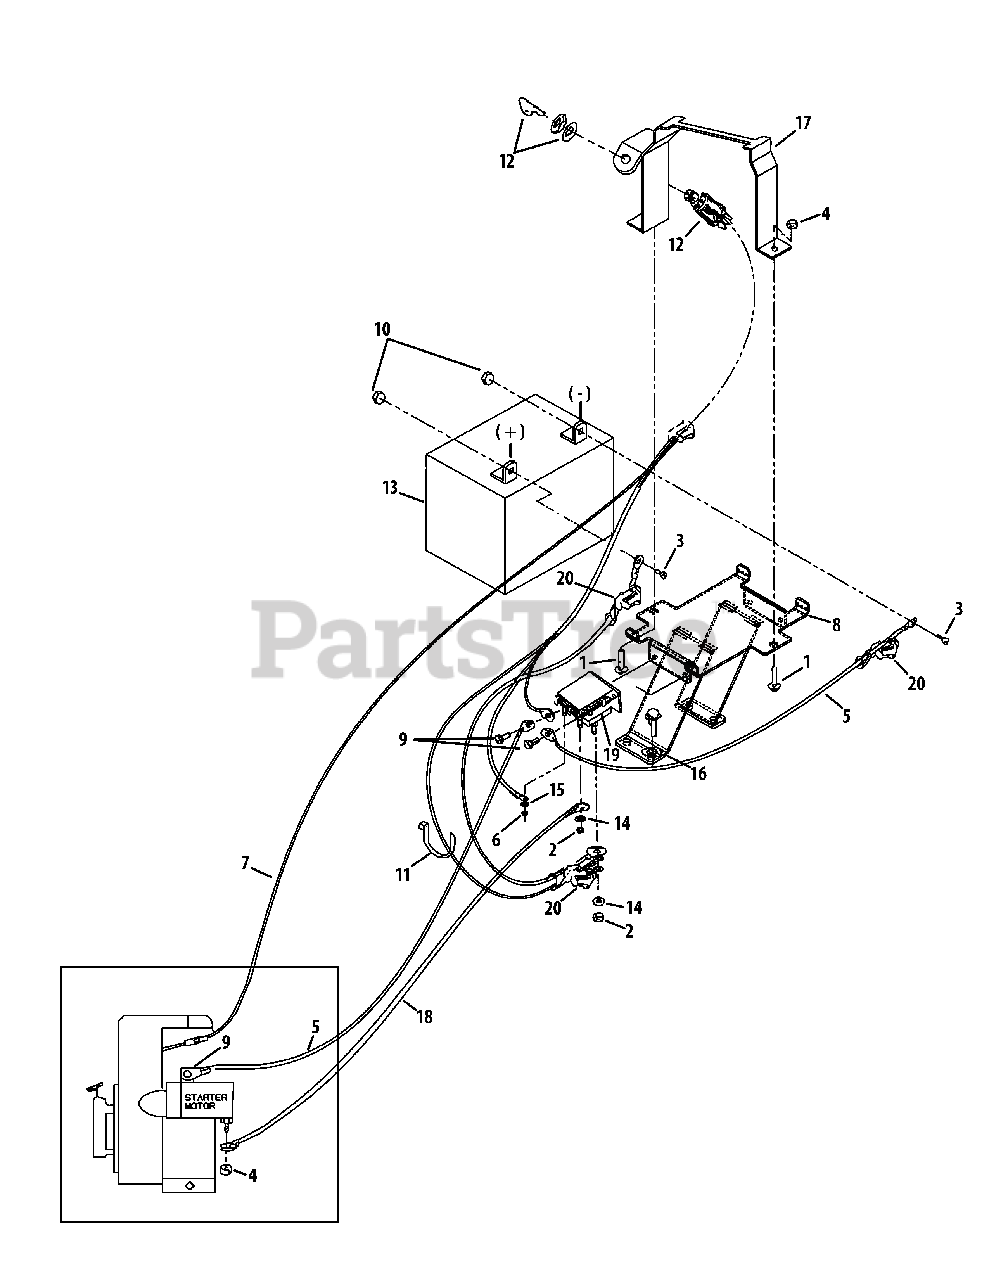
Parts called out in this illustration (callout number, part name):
1	Carriage Screw 1/4-20 x 1.25
2	Hex Nut 5/16-24
3	Flange Screw 1/4-20 x .625
4	Hex Locknut 1/4-20
5	Cable (Ground Wire)
6	Hexlock Washer Nut, 10-32
7	Electric Start Harness
8	Battery Bracket Assembly
9	Self-tapping Screw 1/4-20 x .5
10	Hex Nut 1/4-20
11	Cable Tie
12	Ignition Switch
13	Battery 270 CCA
14	Lock Washer 5/16
15	Lock Washer #10
16	External Lock Washer 5/16
17	Keyswitch Clamp
18	Cable
19	Solenoid
20	Insulating Boot
